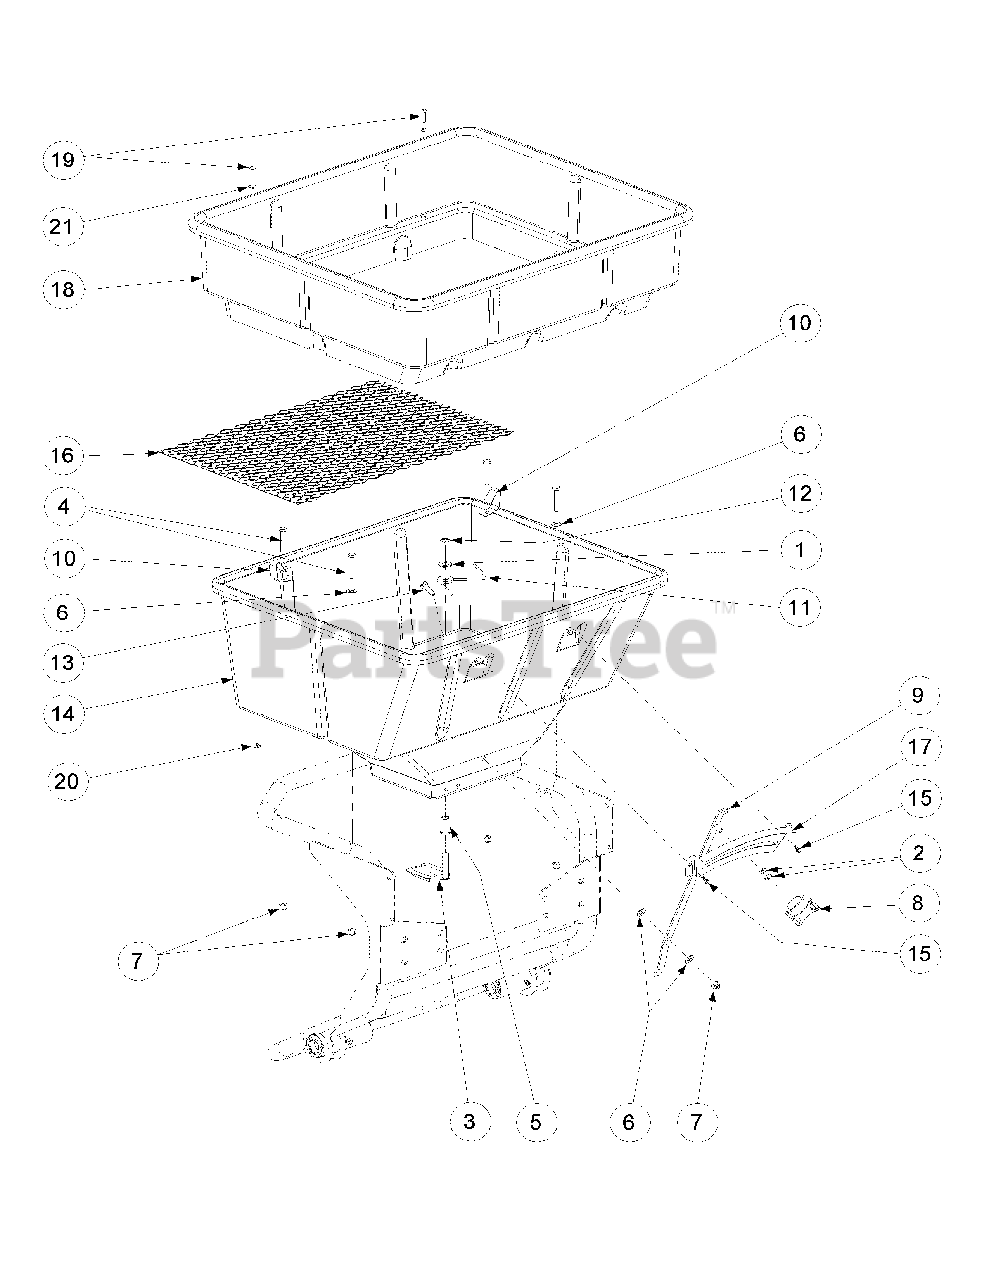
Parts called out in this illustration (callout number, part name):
1	Washer, 3/8
2	Washer, 1/4
3	Cam Agitator Assembly
4	Hex Cap Screw, 1/4-20 x 1.50
5	Agitator Bearing
6	Washer, 1/4, SS
7	Nut, 1/4-20, SS
8	Rate Control Knob
9	Rate Control Arm
10	Screen Clip, SS
11	Agitator Arm Assembly
12	Spring Retainer Clip
13	Machine Screw, 1/4-20 x 7/8
14	80# Hopper
15	Screw, #8 x 3/8, SS
16	Screen, SS
17	Rate Plate
18	Hopper Extension
19	Machine Screw, 10-24 x 3/4, SS
20	Nut, 10-24, SS
21	Washer, #8, SS
22	Decal, Front of Hopper
